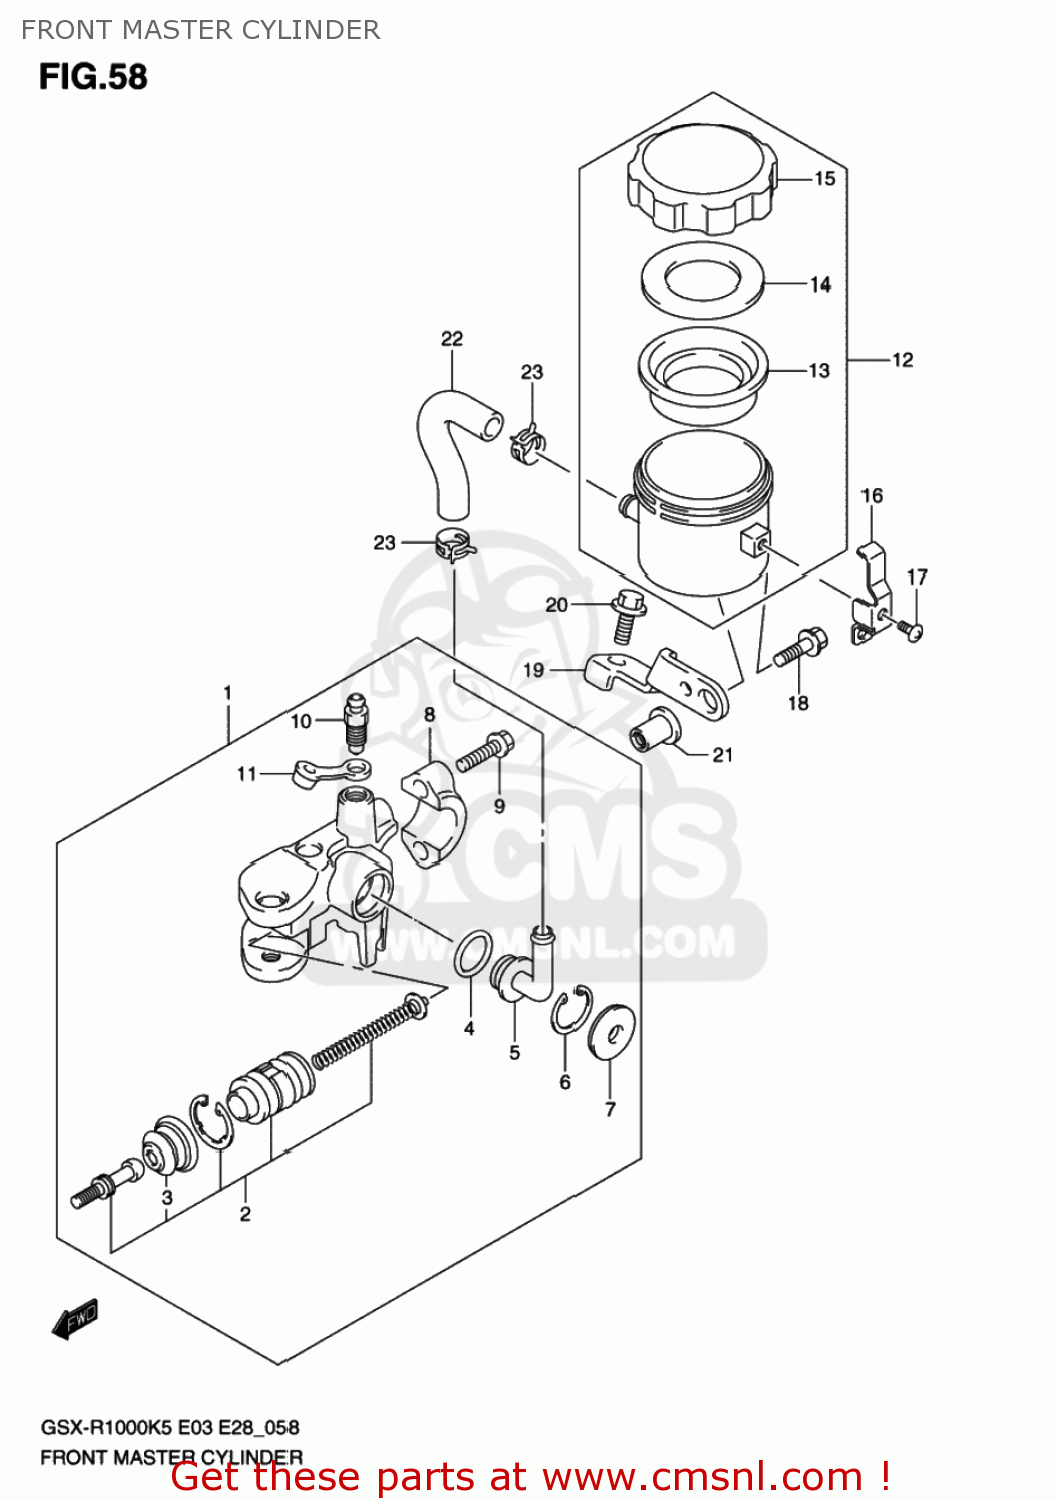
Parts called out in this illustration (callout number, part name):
1	CYLINDER ASSY,
2	PISTON / CUP S
3	BOOT
4	O RING
5	CONNECTOR
6	CIRCLIP
7	COVER,DUST
8	HOLDER
9	BOLT(6X22)
10	BLEEDER
11	CAP,BLEEDER
12	TANK ASSY,RESERVOIR
13	DIAPHRAGM
14	PLATE,DIAPHRAGM
15	CAP
16	PLATE,RESERVOIR TANK CAP
17	SCREW
18	BOLT
19	BRACKET,FR RES
20	BOLT
21	NUT
22	HOSE,FR RESERV
23	CLAMP,RESERVOIR TANK FR
